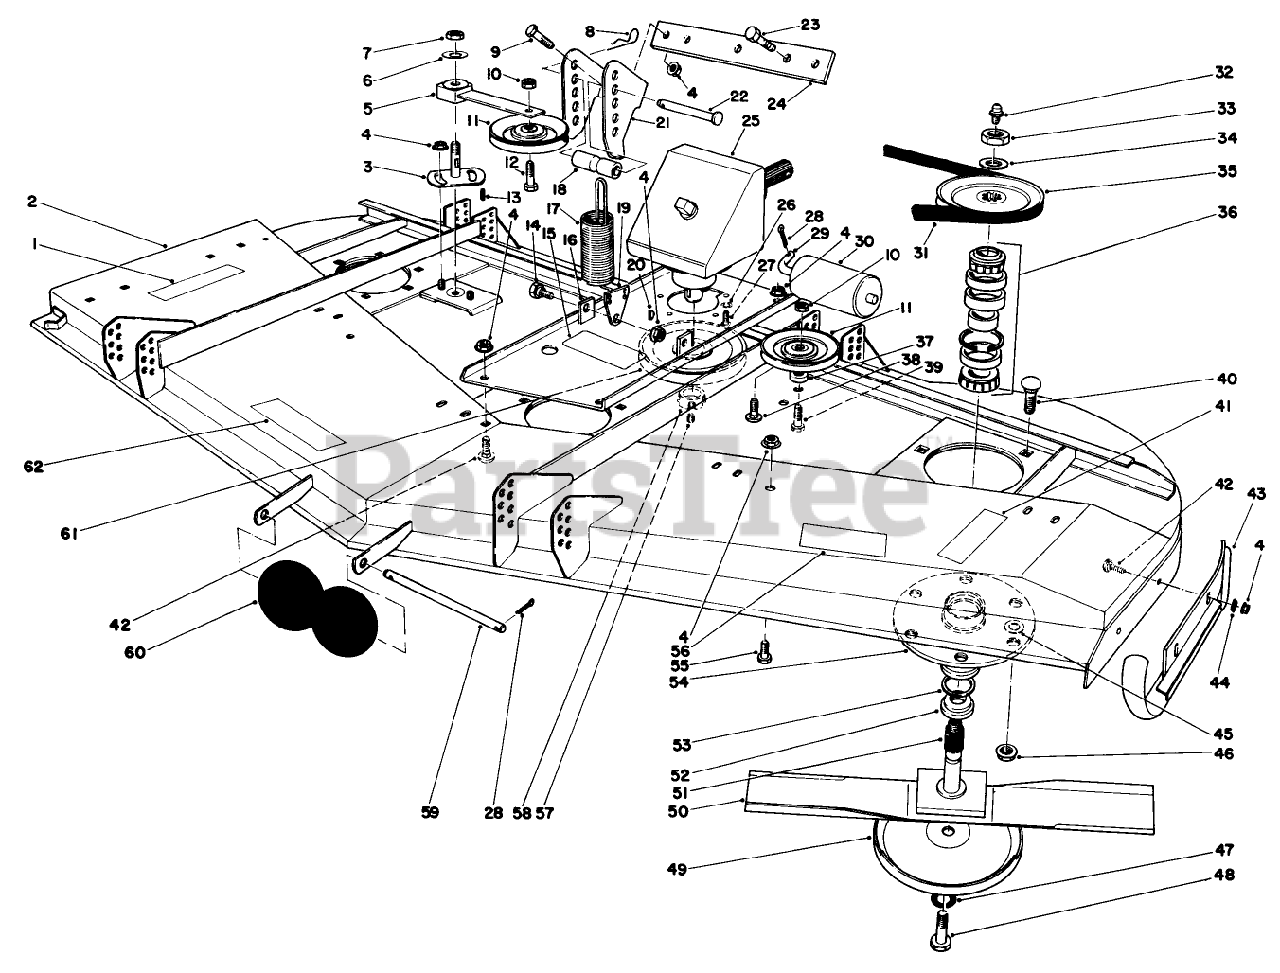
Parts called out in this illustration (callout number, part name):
3	PLATE-IDLER
4	NUT-HHF, WHIZ
6	WASHER-FLAT
7	NUT-LOCK, NI
8	PIN-HAIR
9	SCREW-HH
10	NUT-HEX
12	SCREW-HH
13	KEY-SQUARE
14	BOLT-SHOULDER
16	GEARBOX BASE WA *R
18	SPACER
20	KEY-WOODRUFF
21	SPRING BRACKET *R
22	PIN-CLEVIS
23	SCREW-HH
26	WASHER-LOCK
27	SCREW-HSH
28	PIN-COTTER
29	SHAFT-ROLLER, REAR
30	ROLLER-DECK
31	V-BELT
32	FITTING-GREASE
33	NUT-HEX
34	WASHER
35	PULLEY AND HUB ASM
36	BEARING ASM
37	SPACER
38	SCREW-CARR
39	SCREW-HH
40	SCREW-CARR
41	CAUTION DECAL (BLADE)
42	SCREW-CARR
44	LOCKWASHER-PYRAMID
45	WASHER-FLAT
46	NUT-HF
47	WASHER-LOCK
48	SCREW-BLADE
51	SHAFT
52	SPACER
53	SEAL-OIL
55	SCREW-HH
57	SCREW-SET, HSH
58	BUSHING-LOCK, TAPER
59	SHAFT-ROLLER
60	ROLLER
